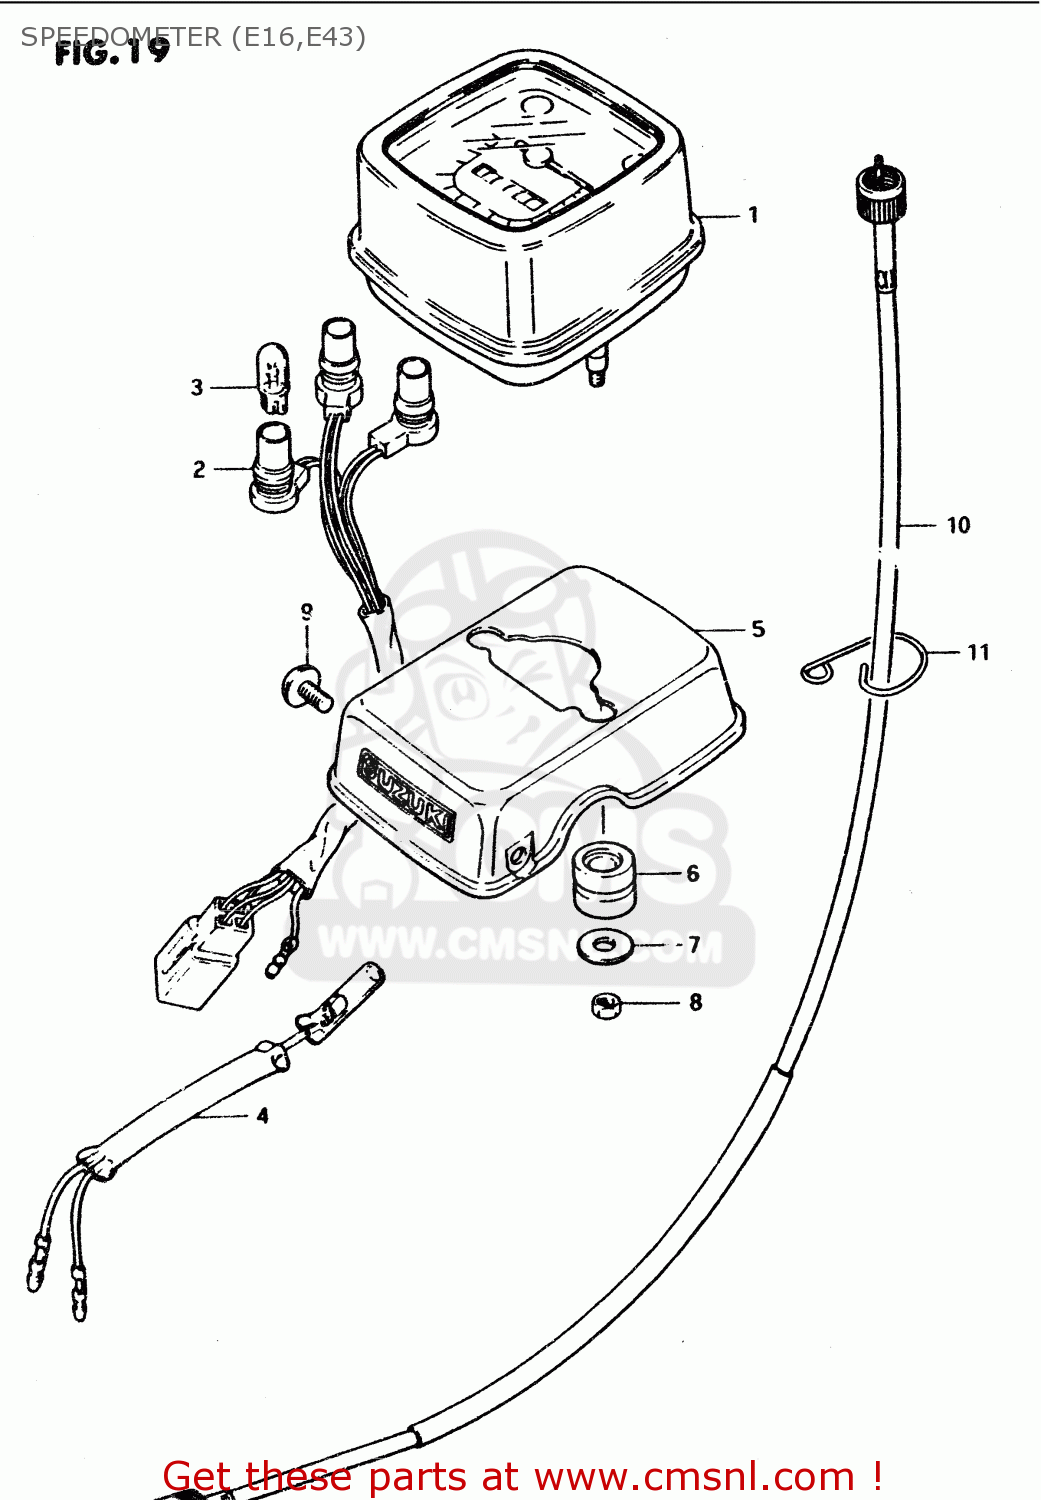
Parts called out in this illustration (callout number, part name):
1	SPEEDOMETER
2	SOCKET
3	BULB(6V,3W)
4	WIRE, LEAD
5	BRACKET,METER
6	CUSHION
7	WASHER (5.5X16X1.2)
8	NUT 5MM
9	SCREW
10	CABLE, SPEEDOMETER
11	CLIP
